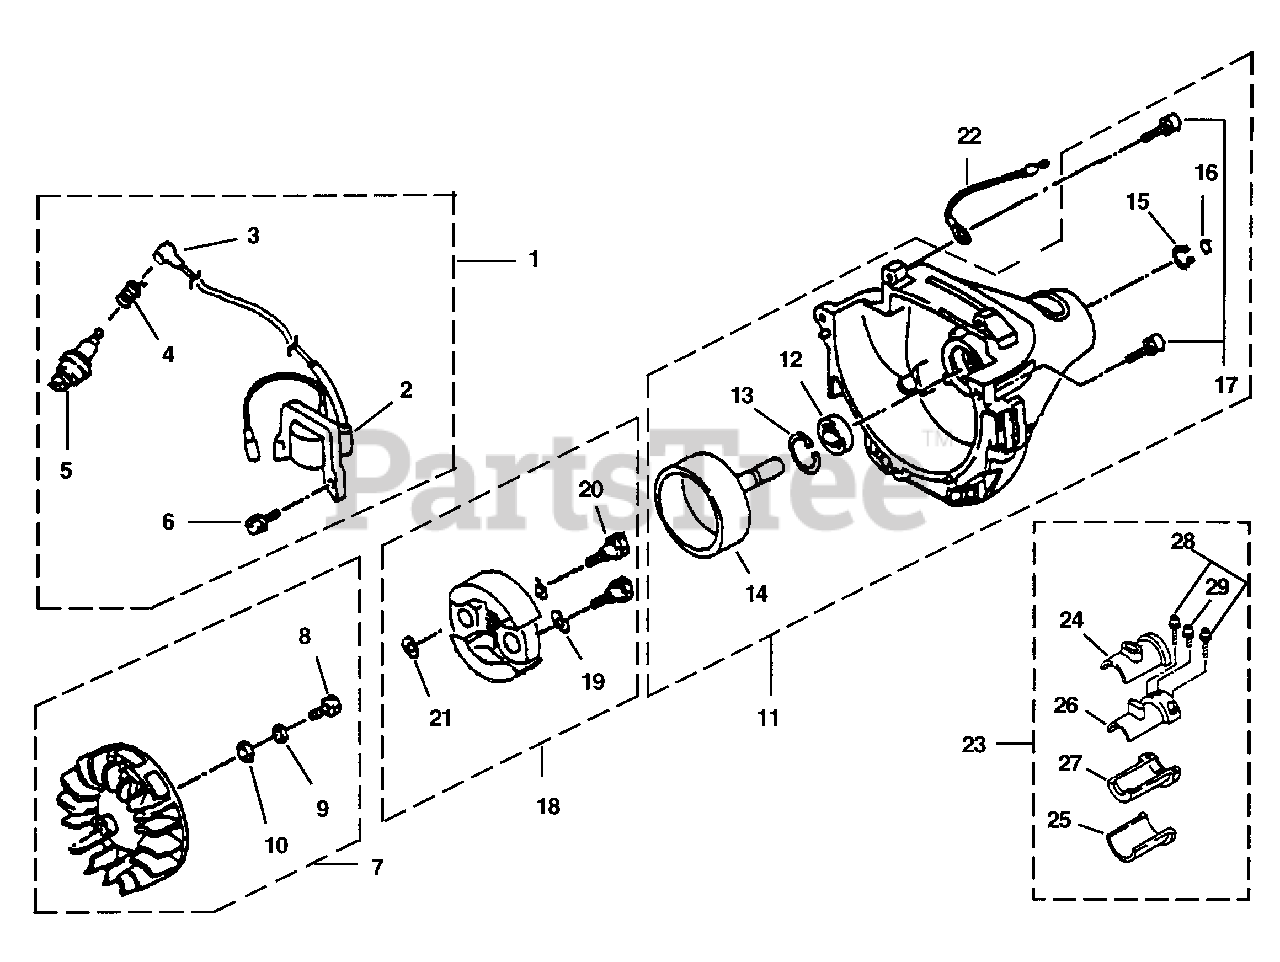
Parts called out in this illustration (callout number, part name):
1	IGNITION KIT
2	MODULE-Ignition
3	CAP-Plug
4	SPRING-Plug Cap
5	SPARK PLUG
6	SCREW ASSEMBLY (M5 X 20)
7	ROTOR ASSEMBLY
8	SCREW (M6 x 16)
9	WASHER-Spring
11	CLUTCH HOUSING
12	BEARING-Ball
13	SNAP RING-Inner
14	CLUTCH DRUM
15	SNAP RING-Outer
17	SCREWS-Socket Hd (M5 x 20W SW)
18	CLUTCH ASSEMBLY
20	BOLT-Clutch (M6 x 25)
23	DRIVESHAFT ISOLATOR ASSEMBLY
26	ISOLATOR
27	ISOLATOR
28	SCREW-Socket Hd (M5 x 18 SW)
29	SCREW-Socket Hd (M5 x 12 SW)
